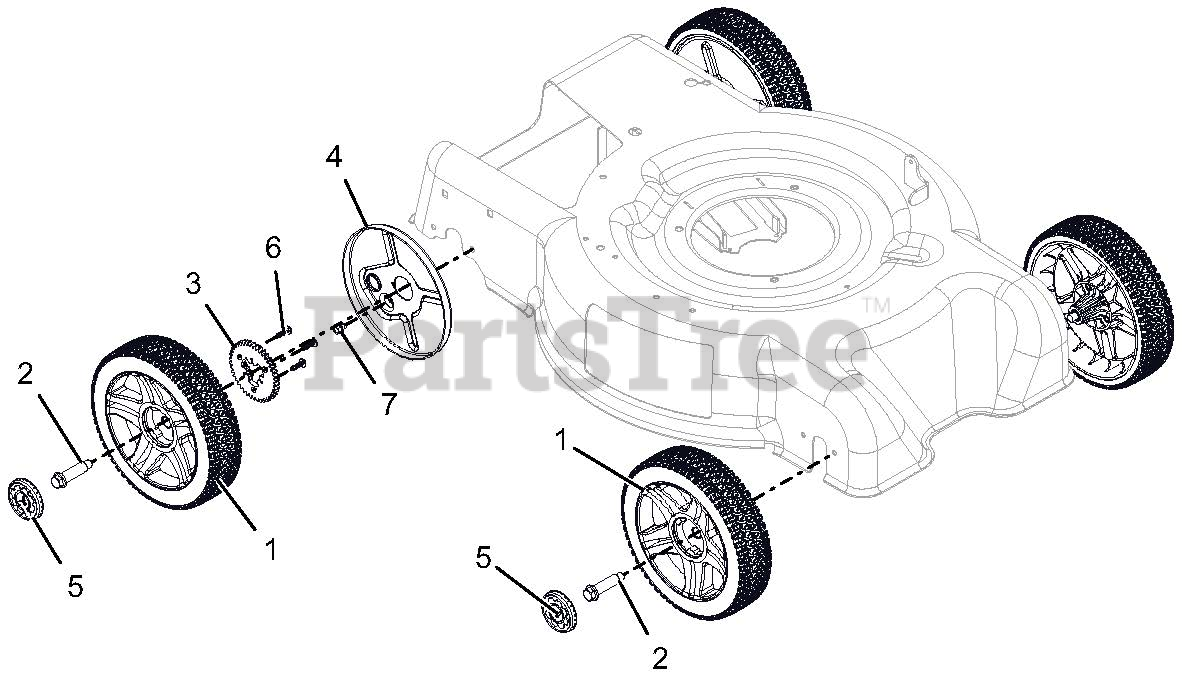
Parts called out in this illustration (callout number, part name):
1	ASSEMBLY, RAZOR WHEEL/BSHG
2	BOLT, WHEEL SHOULDER
3	GEAR, WHEEL
4	COVER, WHEEL
5	CAP, LM WHEEL HUB
6	SCR-TAP 12-14X.75PLSTITE @BLZC
7	@SCR-TAP .25-20X.37 HWH YWZ TR
